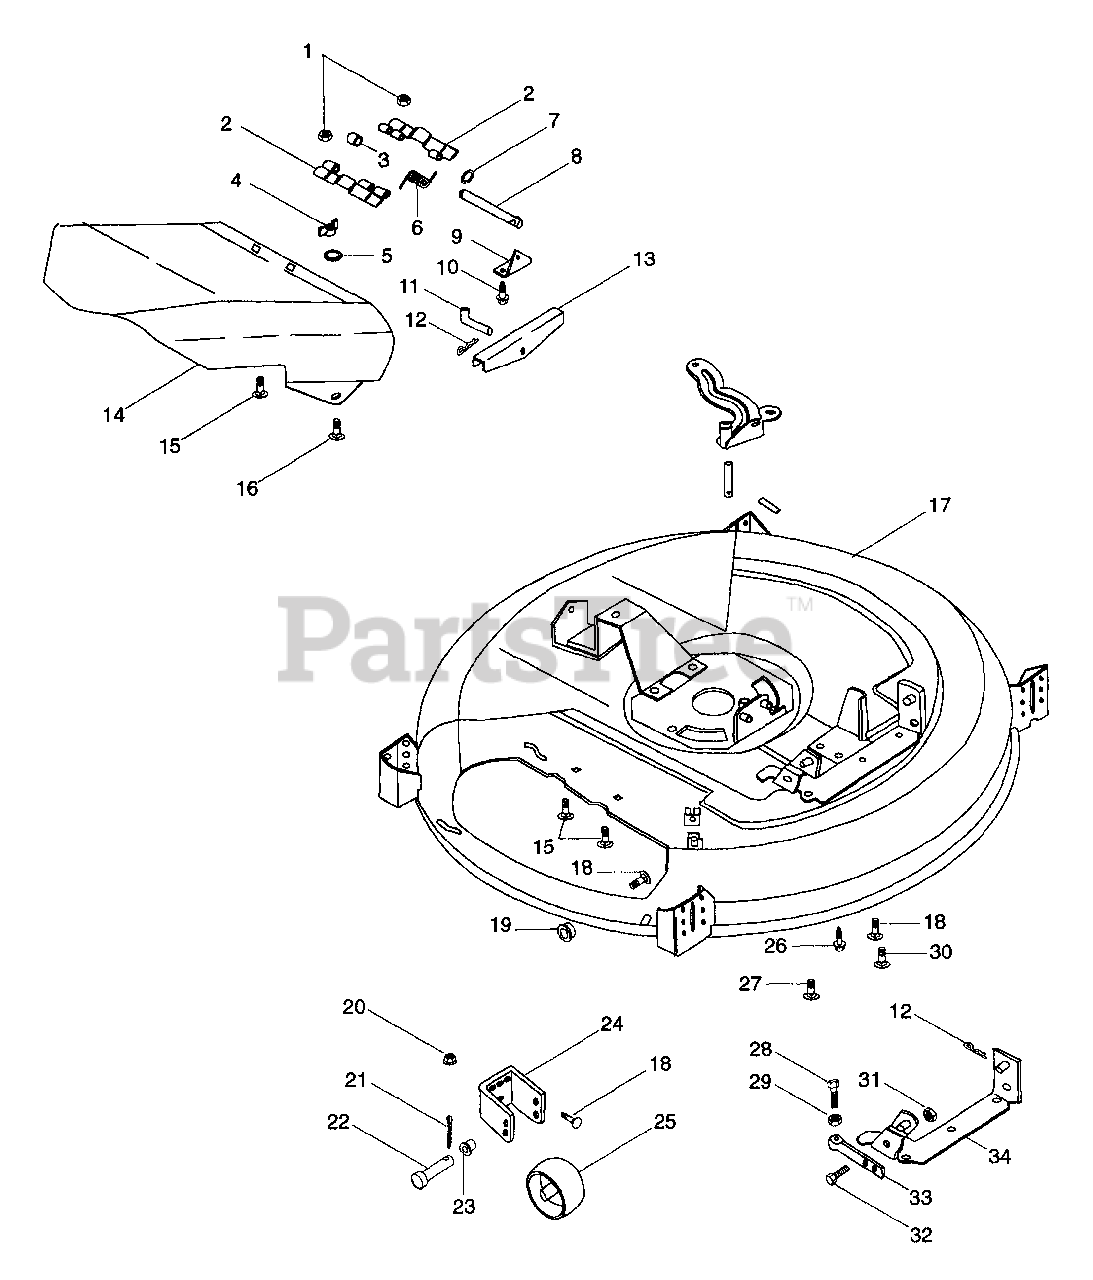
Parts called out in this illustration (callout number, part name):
1	NUT-LK-CTR .250-20 PL
2	HINGE PLATE
3	BSHG-SLV .334 X .502 X 1.437
4	NUT-WING W/INSERT .312 - 18
5	WSHR-FL-STL .328X.875X.062 PL
6	SG-TORS .095X.50X 1.0
6	SG-TORS .090X.37X.63
7	RG-RTNG-EXT .312X.025
9	REAR MOUNTING BRACKET
10	SCR-TAP .312-18X.50 HWH PL TR
11	CLEVIS PIN
12	PIN-HAIR INT .08X.38X1.42 YWZC
13	TUBE WELDMENT
14	PAN CHUTE EXTENSION
14	28" DEFLECTOR W/DECALS
14	32" DEFLECTOR W/DECAL
15	BLT-RDHDSQNK .25-20X.62 PL
16	BLT-RDHDSQNK .25-20X1.00 GR5
17	28"MOWER PAN W/DEFLECTOR&DECAL
17	28" MOWER PAN SERVICE ASSEMBLY
17	30"MOWER PAN W/DEFLECTOR&DECAL
17	30" MOWER PAN ASSEMBLY
17	32"MOWER PAN W/DEFLECTOR&DECAL
17	32" MOWER PAN ASSY RETROFIT
18	BLT-RDHDSQNK .312-18X.62SHTPL
19	NUT-PUSH .312
20	NUT-FLG. .312-18 PL
21	PIN-COTR .15 X 1.0 PL
22	PIN-CLEV .371X3.25 YWZC
23	BSHG-FLG .372X.500X.312X.625NY
24	ROLLER CLEVIS
25	ROLLER
26	SCR-TAP .375-16X .50 HWH PL TR
27	BLT-RDHDSQNK .31-18X1.00 PL
28	BLT-HEX .38-16X1.25 PL GR5
29	NUT-JAM .375-16 PL
30	BLT-RDHDSQNK .25-20X.75
31	NUT-LK-CTR .375-16 GR A PL
32	@BLT-HEX .38-16X.88 PL GR2
33	ADJUSTING ARM
34	FRONT BRACKET 30"
